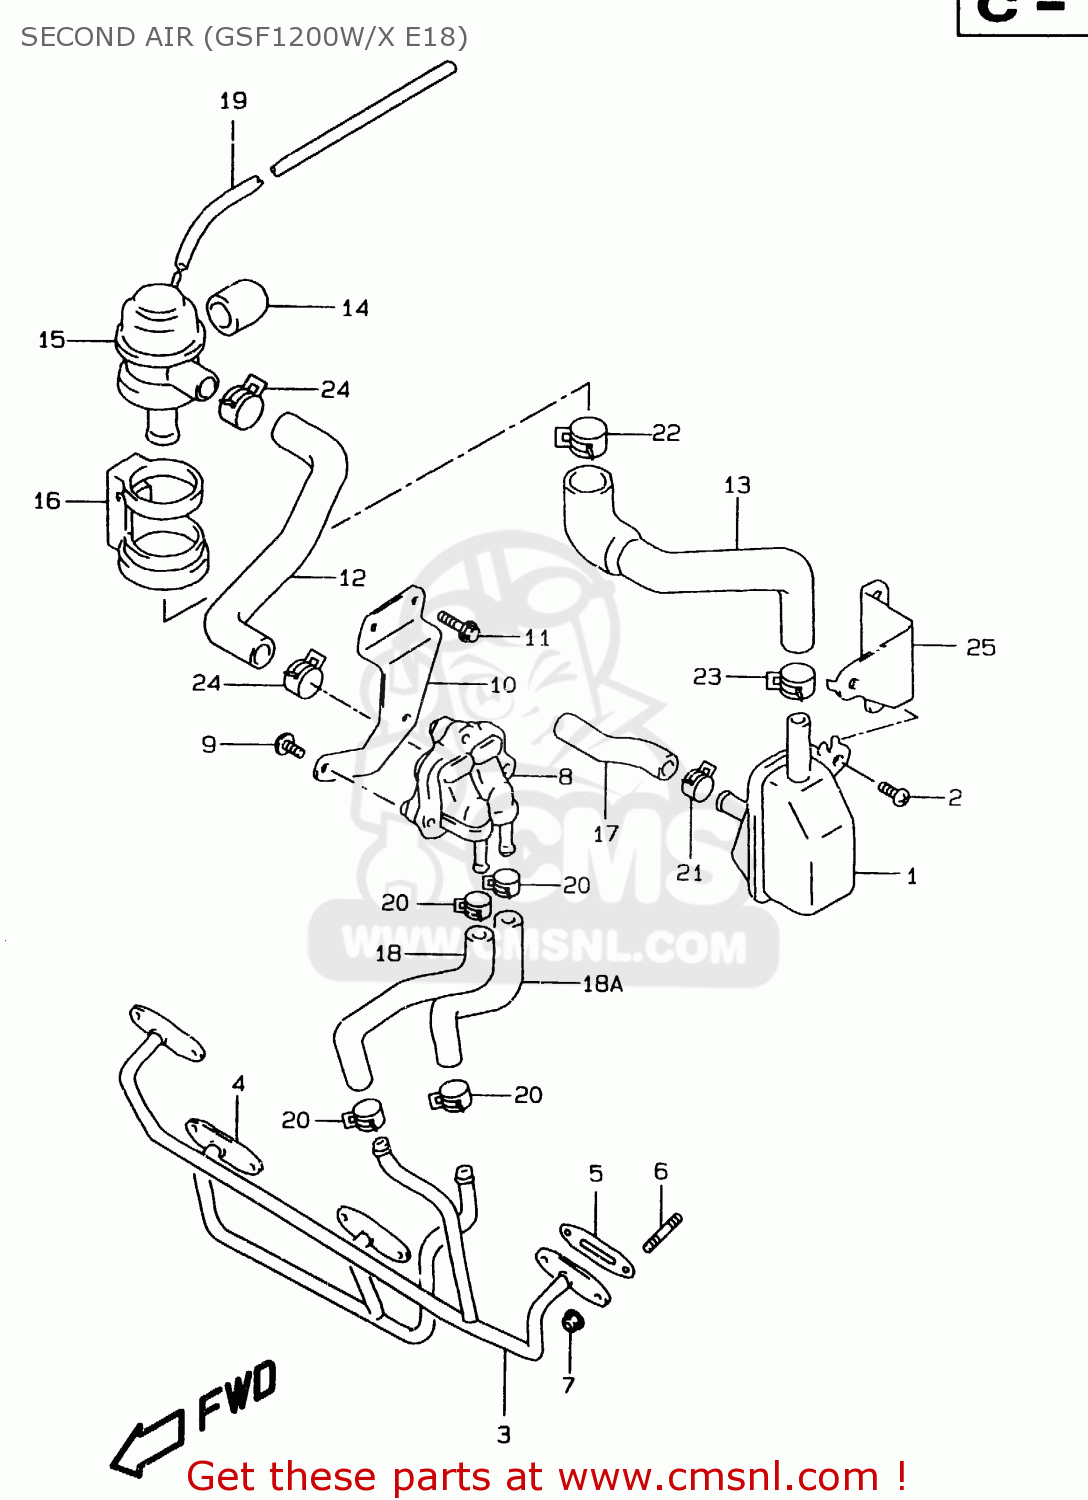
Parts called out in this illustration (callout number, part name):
1	CLEANER ASSY,2ND AIR
2	SCREW
3	PIPE COMP,SECOND AIR,OUTER
4	PIPE COMP,SECOND AIR,INNER
5	GASKET,SECOND AIR PIPE (NAS)
6	STUD BOLT
7	NUT
8	VALVE ASSY,2ND AIR REED
9	BOLT
10	BRACKET, REED VALVE
11	BOLT
12	HOSE, 2ND AIR SW VALVE
13	HOSE, 2ND AIR CLEANER
14	CAP,SWITCHING VALVE
15	VALVE ASSEMBLY,SECOND AIR SWITCH
16	CUSHION,2ND AIR VALVE
17	HOSE(12X16X600)
18	HOSE, 2ND AIR REED VALVE, RH
18A	HOSE, 2ND AIR REED VALVE, LH
19	HOSE(4X7X600)
20	CLIP
21	CLIP
22	CLIP
23	CLIP
24	CLIP
25	BRACKET, 2ND AIR CLEANER
